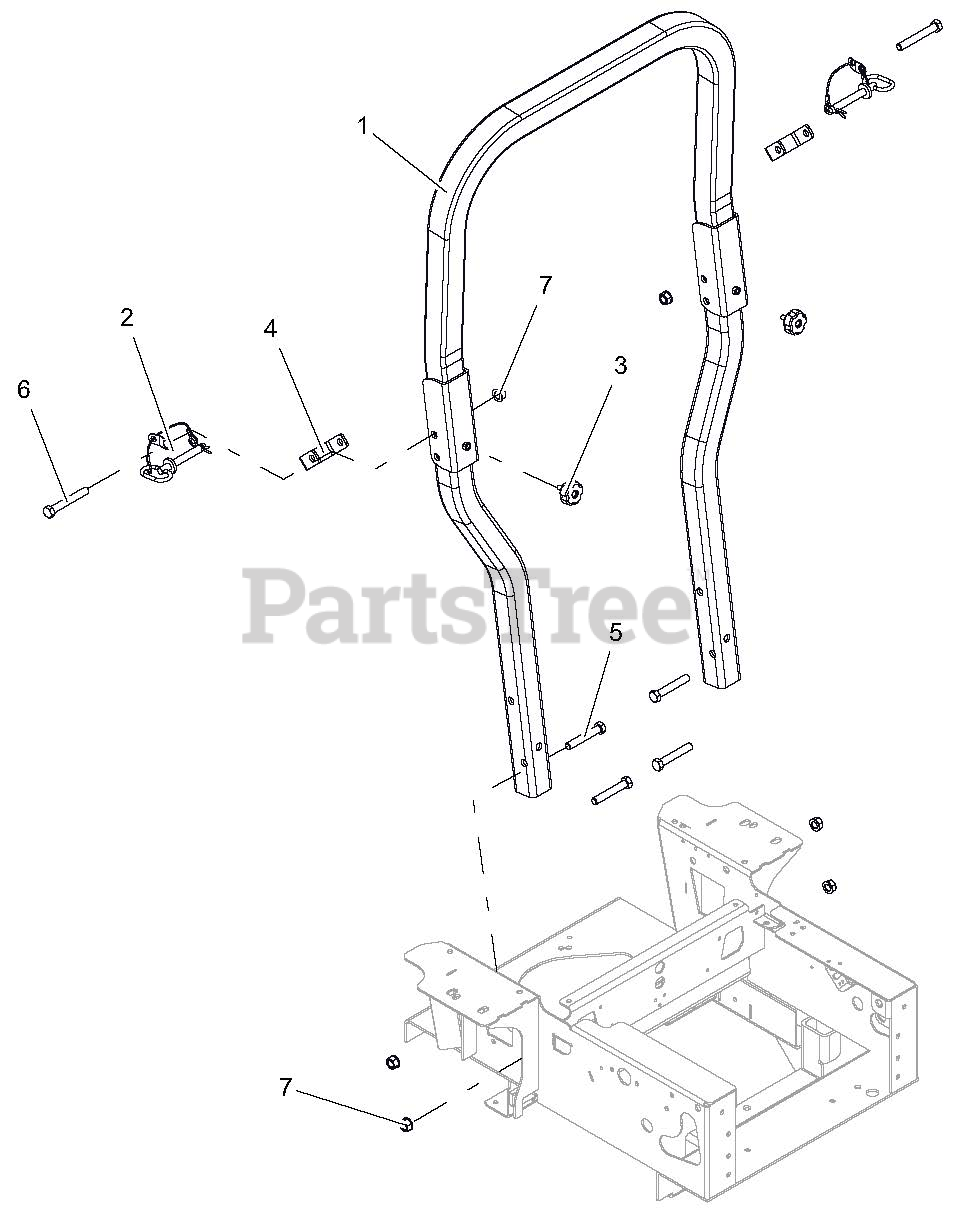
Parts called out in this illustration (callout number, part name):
1	ROPS, PT/PT100 REPLACEMENT
2	ASSY, ROPS PIN/LANYARD
3	KNOB, ROUND 5/16-18 X .750
4	BRKT, ROPS STOP, PRO-TURN YZ
5	BLT-HEX .50-13X3.00 GR5 YWZC
6	BLT-HEX .50-13X3.50 GR5 YWZC
7	NUT, LK-TOP-FLG .50-13 YWZC
